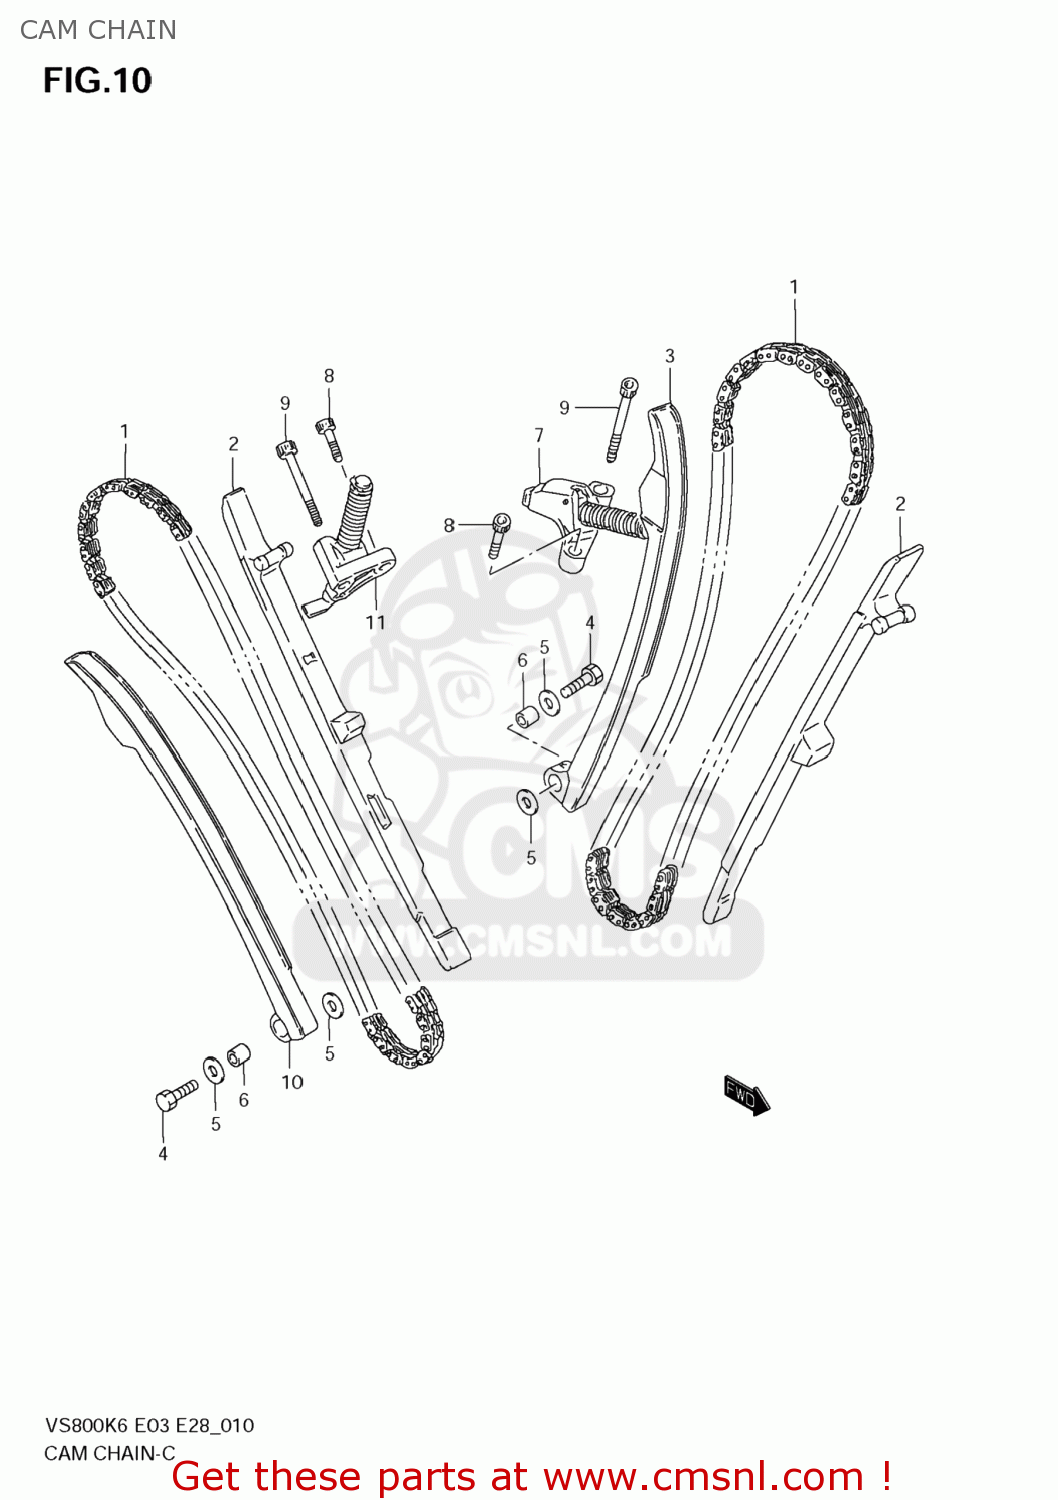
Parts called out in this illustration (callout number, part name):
1	CHAIN COMP,CAMSHAFT DRIVE
2	GUIDE,CAM CHAIN
3	TENSIONER,FR CAM CHAIN
4	BOLT(6X26)
5	WASHER
6	SPACER(6X11X11)
7	ADJUSTER ASSY,FR TENSIONER
8	BOLT
9	BOLT
10	TENSIONER,RR CAM CHAIN
11	ADJUSTER ASSY,RR TENSIONER
